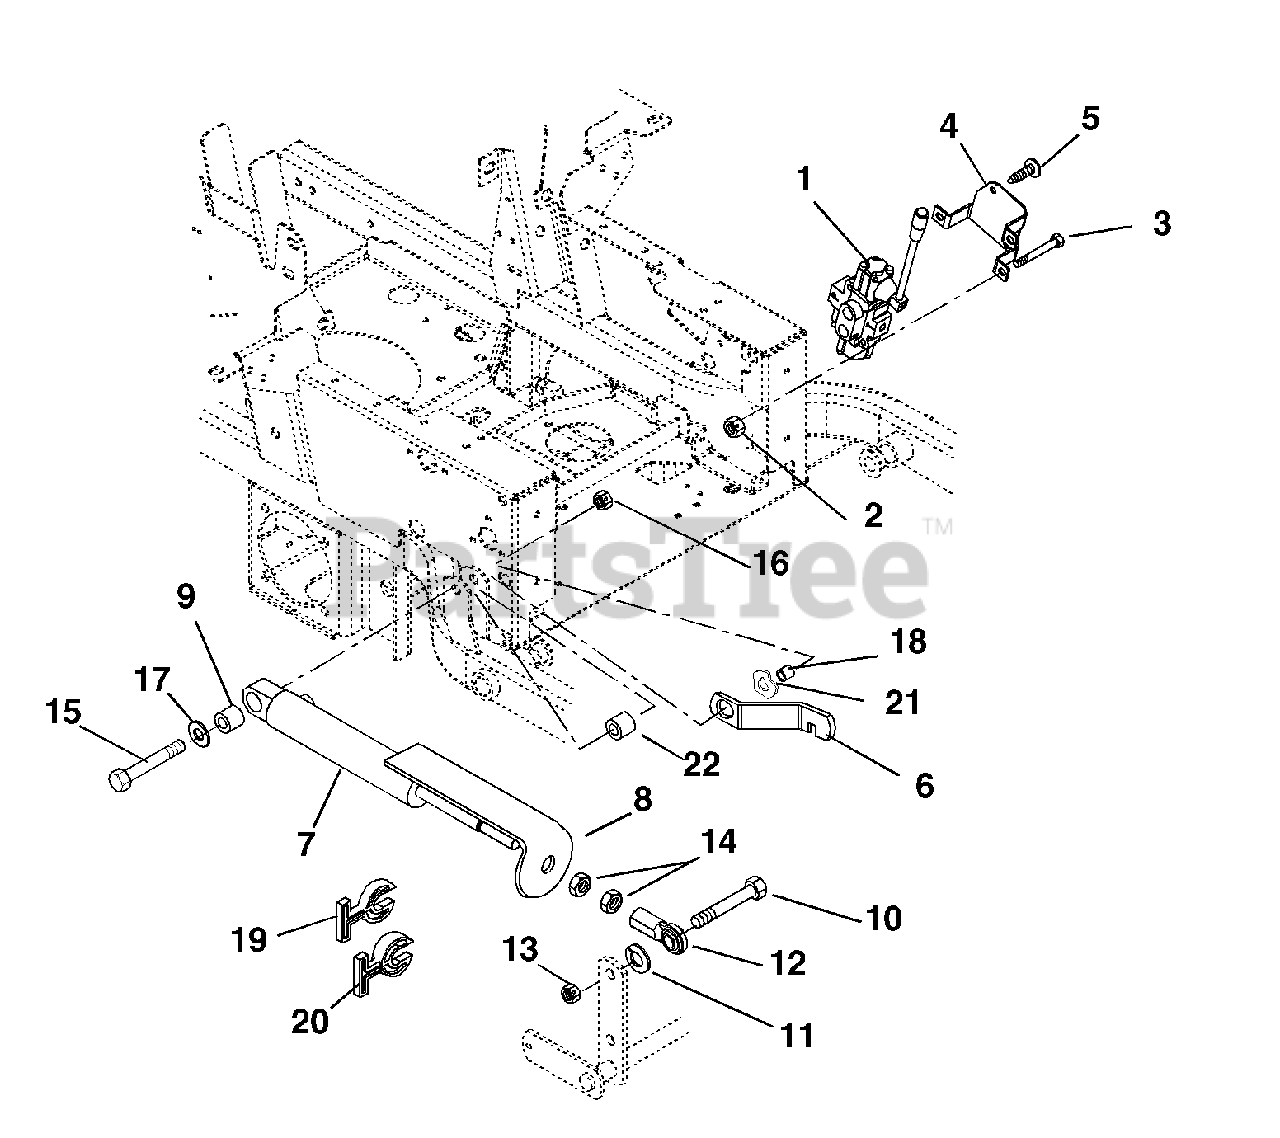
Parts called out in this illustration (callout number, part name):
1	VALVE, HYDRAULIC
2	@NUT-LK-TOP-FLG .31-18 YWZC
3	@BLT-HEX .31-18X2.25 GR5 YWZC
4	VALVE MOUNTING BRACKET -BLACK
5	@SCR-TAP .38-16X.50 HWH TR YWZ
7	CYLINDER - HYDRAULIC LIFT
8	STRAP, CUT INDICATOR/GUARD
9	BUSHING, .516X1.000X1.050 LG
10	BLT-HEX .62-11X2.25 YWZC GR8
11	@WSHR-LK .62X.156 REG YWZC
12	ROD END, 5/8 RH - FEMALE
13	@NUT-LK-CTR .62-11 YWZC
14	NUT-JAM .625-18 YWZC
15	POST, CYLINDER STOP
16	@NUT-LK-TOP-FLG .50-13 YWZC
17	WSHR-FL-STL .515X1.625X.250 YZ
18	BSHG-FLG .515X.750X.285X1.120
19	STOP, CYLINDER .34 THK
20	STOP, CYLINDER .680 THK
21	WASHER-WAVE .760X1.120X.080
22	SPACER .516X1.000X.875
